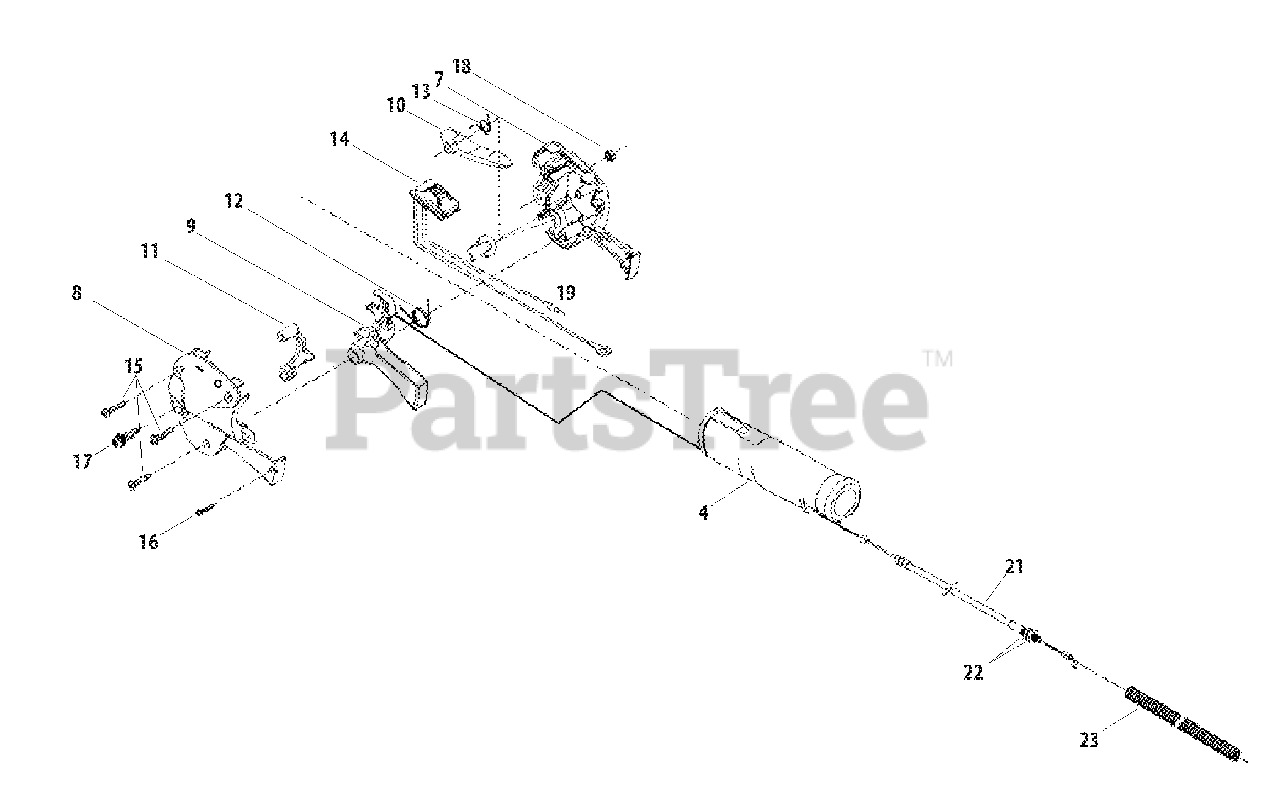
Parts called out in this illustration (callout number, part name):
4	GRIP
7	CONTROL HANDLE - RIGHT
8	CONTROL HANDLE - LEFT
9	TRIGGER, THROTTLE
10	LEVER, LOCK
11	LOCKOUT, THROTTLE
12	SPRING, THROTTLE RETURN
13	SPRING, THROTTLE LOCKOUT
14	SWITCH, ON-OFF
15	SCREW, TAPPING M4×20
16	SCREW, TAPPING 3×14
17	SCREW M5×20
18	NUT M5
19	PLUG
21	CABLE, THROTTLE
22	NUT M6
23	TUBE, PLASTIC PROTECTIVE
